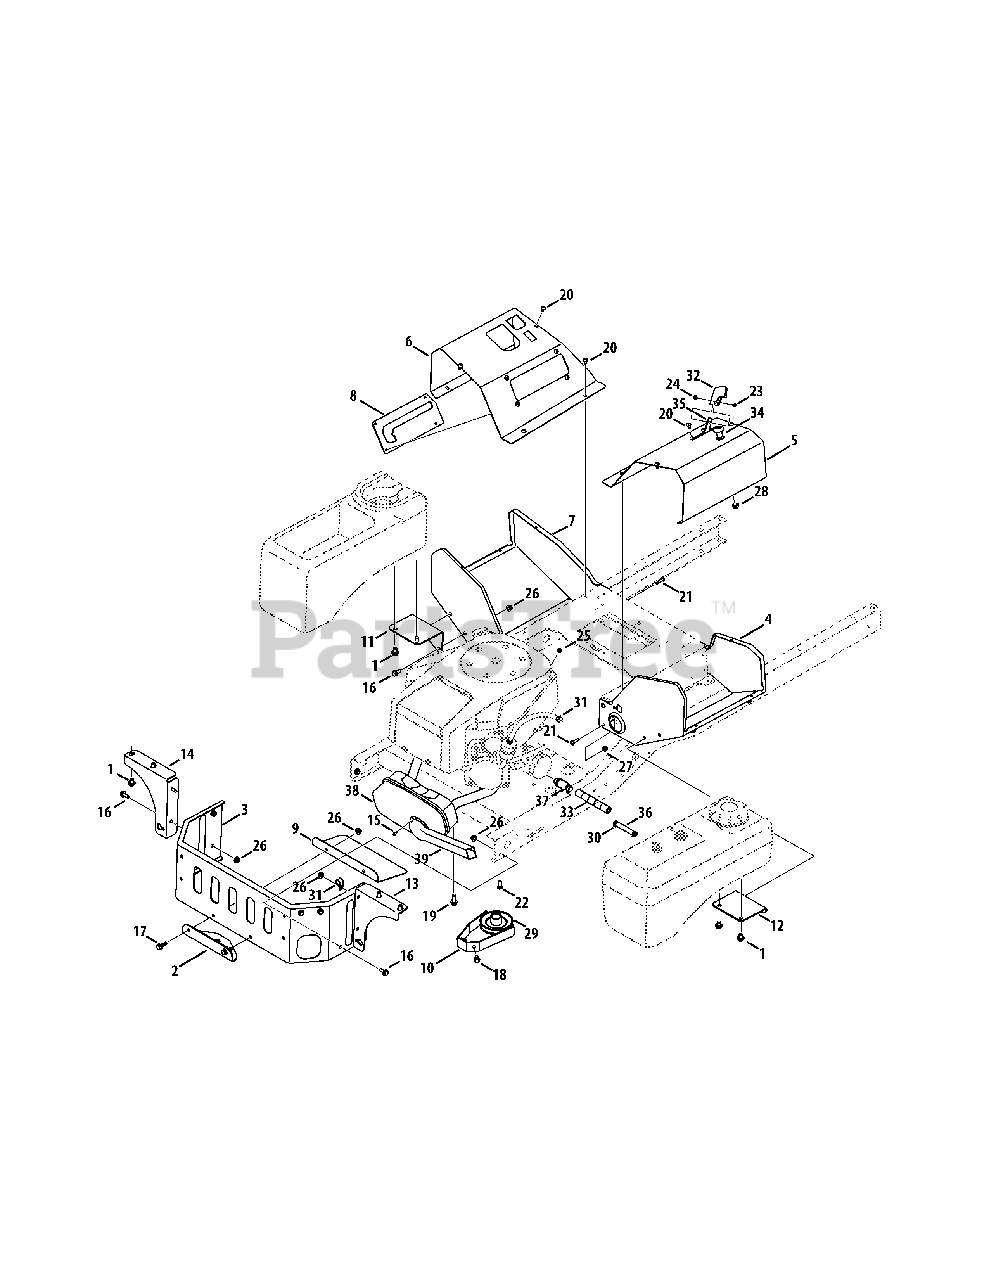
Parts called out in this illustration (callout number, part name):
1	Hex Washer Screw, 3/8-16 x .500
2	Hitch Bracket
3	Bumper Bracket
4	RH Lower Console
5	RH Upper Console
6	LH Upper Console
7	LH Lower Console
8	Parking Brake Lock Bracket
9	Muffler Mount Bracket
10	Belt Keeper Bracket
11	Left Tank Support Bracket
12	Right Tank Support Bracket
13	Tank Support Bracket RH
14	Tank Support Bracket LH
15	Hex Washer Screw, #8-18 x 0.500
16	Hex Flange Screw, 5/16-18
17	Hex Flange, 5/16-18 x 1.0
18	Hex Washer Screw, 5/16-18 x .750
19	Tap Screw, 3/8-16 x 1.00
20	Screw, 1/4-20 x .5
21	Screw, 1/4-20 x 1.0
22	Hex Head Screw, 5/16-18 x .75
23	Machine Screw, #8-32 x0.375
24	Hex Nut, #8-32
25	Sems Nut, 1/4-20
26	Flange Lock Nut, 5/16-18
27	Flange Lock Nut, 1/4-20
28	Flange Lock Nut, 3/8-16
29	Electric PTO Engine Pulley
30	Hose Clamp, .490
31	Clamp, 9/16
32	Throttle Knob
33	Oil Drain Extension Hose
34	Choke Cable
35	Throttle Cable, 39.0 x .62
36	Fuel Hose, 1/4
38	Kohler Twin Muffler
39	Long Muffler Deflector
